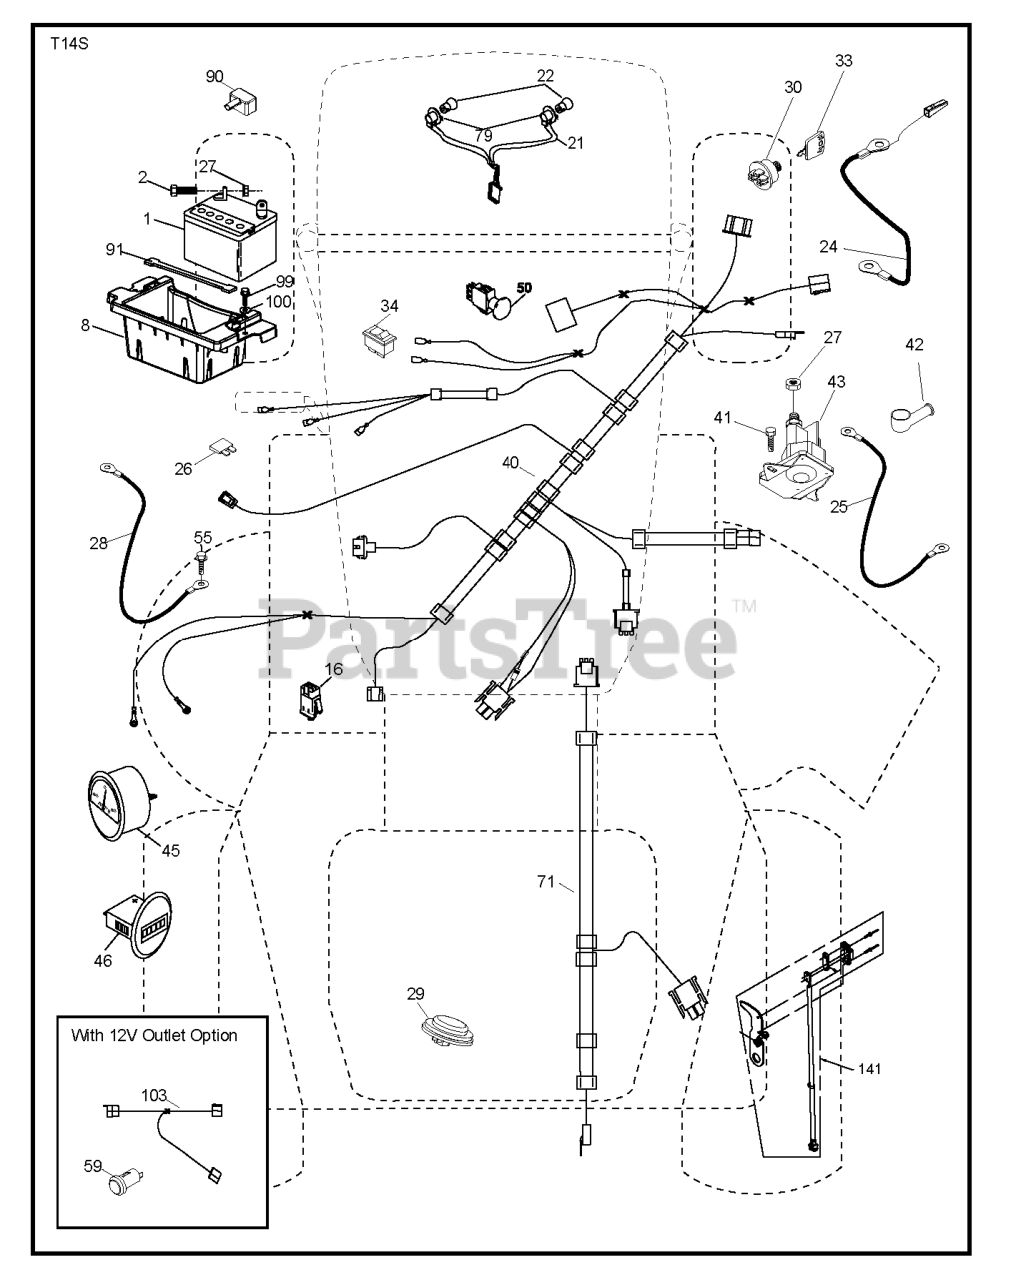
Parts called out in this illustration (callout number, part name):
1	Battery 12 Volt 25 Amp
2	BOLT.HEX.1/4.X.3/4.DICHROMATE
8	BOX.BATTERY.MOUNT.FRONT.LT
16	SWITCH INTERLOOK PUSH-IN
21	HARNESS.LIGHT W/4152J BULBS
24	CABLE.BATT.POS.WIRE.TG.DA SOL
25	CABLE.STARTER.6G.BL/RED.17.5
26	FUSE 20AMP
27	NUT
28	CABLE GROUND 6 GA 21" 90T BLK
29	SWITCH.SEAT.DELTA.OPC.
30	SWITCH.IGN.DELTA.W.LGH.ROS
33	KEY.CHAIN.BLISTER.PACK.GEN.INT
40	HARNESS IGN. DASH
41	SCREW
42	TERMINAL COVER
43	SOLENOID.W/BRASS.PLUNGER
45	AMMETER GAUGE ROUND SNAP-IN
46	HOURMETER.GAUGE.RNK.SNAP.LS
50	RP.PTO.SWITCH.8 TERMINAL.BLACK
55	SCREW 5/16"
59	OUTLET.12-VOLT
71	HARNESS-CHASSIS SUB
79	BULB HOLDER ASM.
90	COVER.TERMINAL.BATTERY
91	STRAP.BATTERY.MOUNT.FRONT(2 2)
99	SCREW HEXWSHR 1/4-20X3/4
103	HARNESS.PIGTAIL.12V.OUTLET.
141	KIT.G700/G730.ROS 71750
